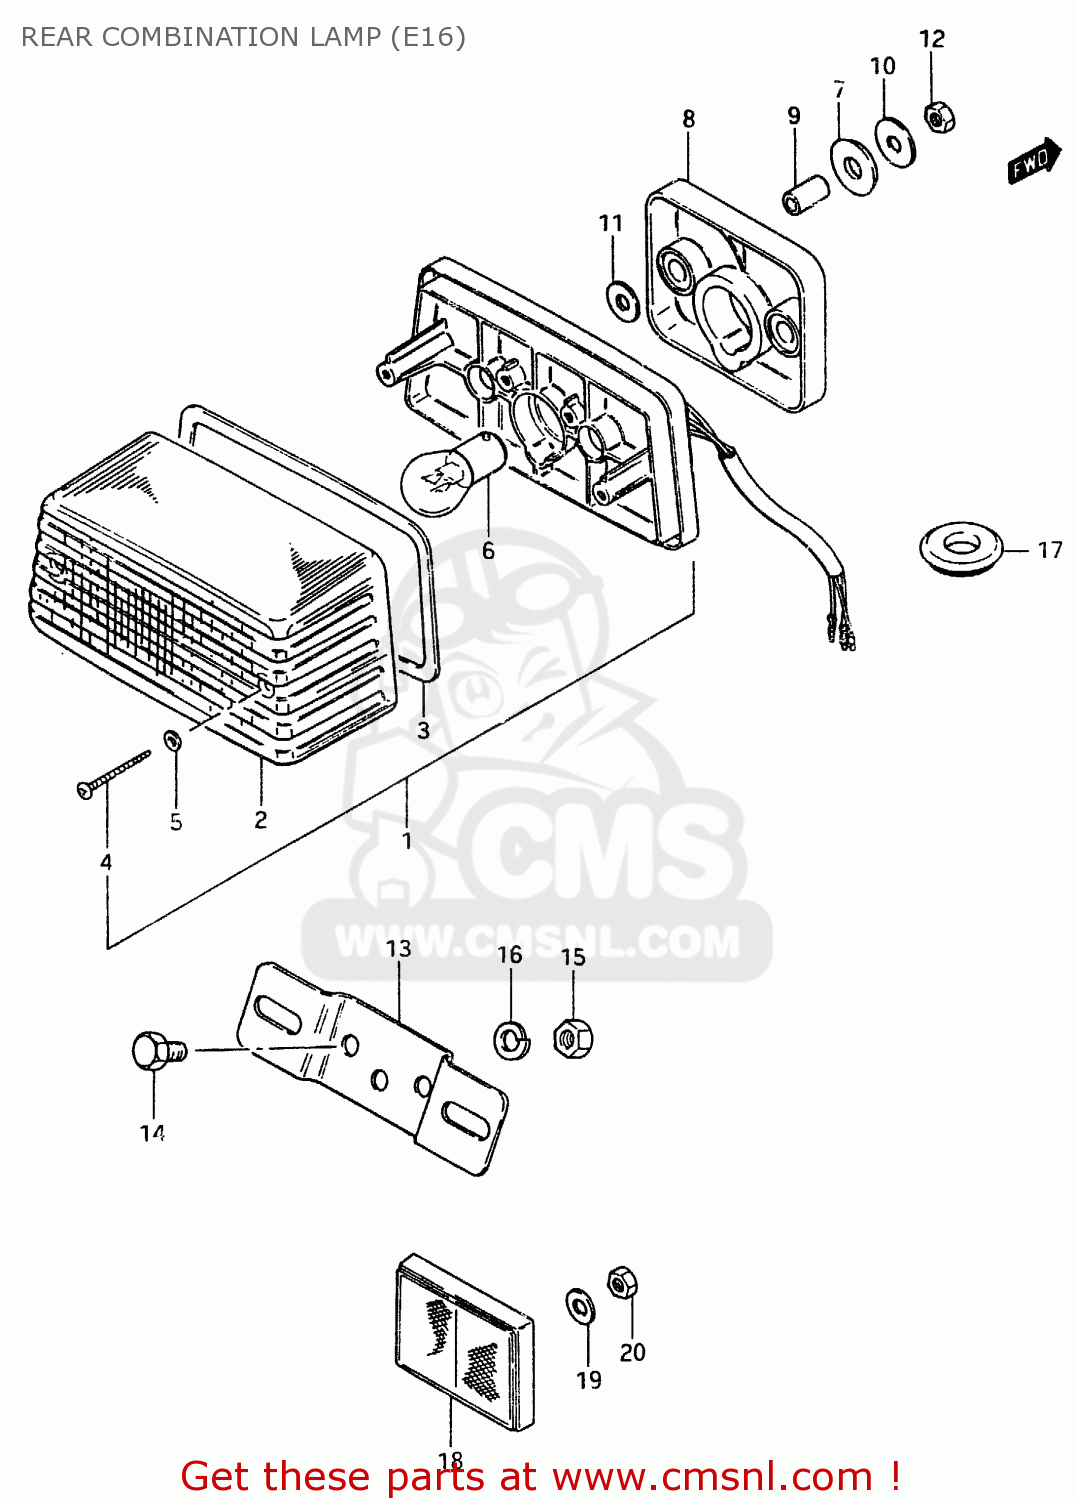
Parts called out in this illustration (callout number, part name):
1	LAMP ASSY, TAIL
2	LENS
3	GASKET (NAS)
4	SCREW
5	GASKET (NAS)
6	BULB(6V10/3W,STANLEY,A4854H)
7	CUSHION
8	CUSHION
9	SPACER
10	WASHER (5.5X20X1.2)
11	WASHER(5.2X16X1)
12	NUT
13	BRACKET, LICENSE PLATE
14	BOLT
15	NUT
16	LOCK WASHER
17	GROMMET
18	REFLEX REFLECTOR,RR
19	WASHER(5.2X16X1)
20	NUT
